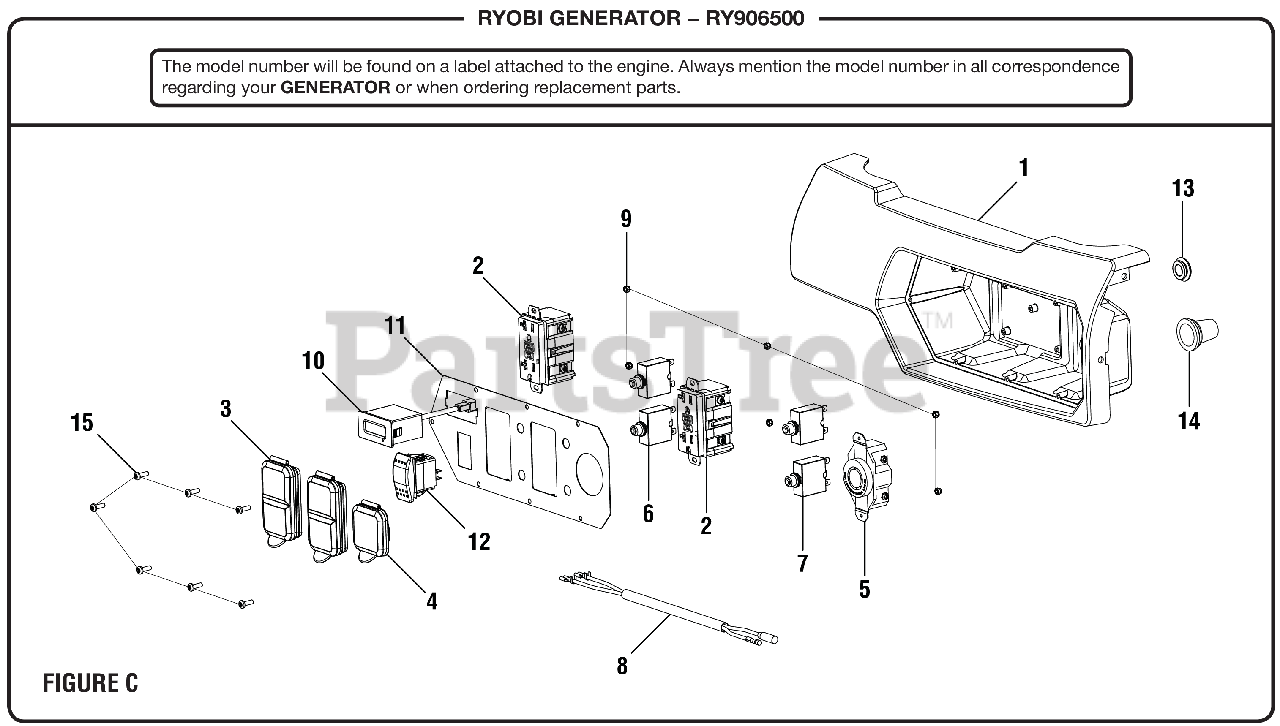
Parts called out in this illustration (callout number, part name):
1	Control Box (Back Panel)
2	Duplex Receptacle (120 Volt)
3	120 Volt Receptacle Rain Cover
4	240 Volt ReceptacleRain Cover
5	Twist Lock Recepticle (120/240 Volt, 30 Amp, L14-30)
6	Circuit Breaker (20 Amp, 125 Volt)
7	Circuit Breaker 30 Amp 1 Pole
8	Wiring Harness
9	Lock Nut (6-32, Hex Hd.)
10	Digital Display
11	Faceplate
12	Stop Switch
14	Wiring Rubber Boot
15	Screw (#8-18 x 1/2 in., T20 Torx Pan Hd.)
